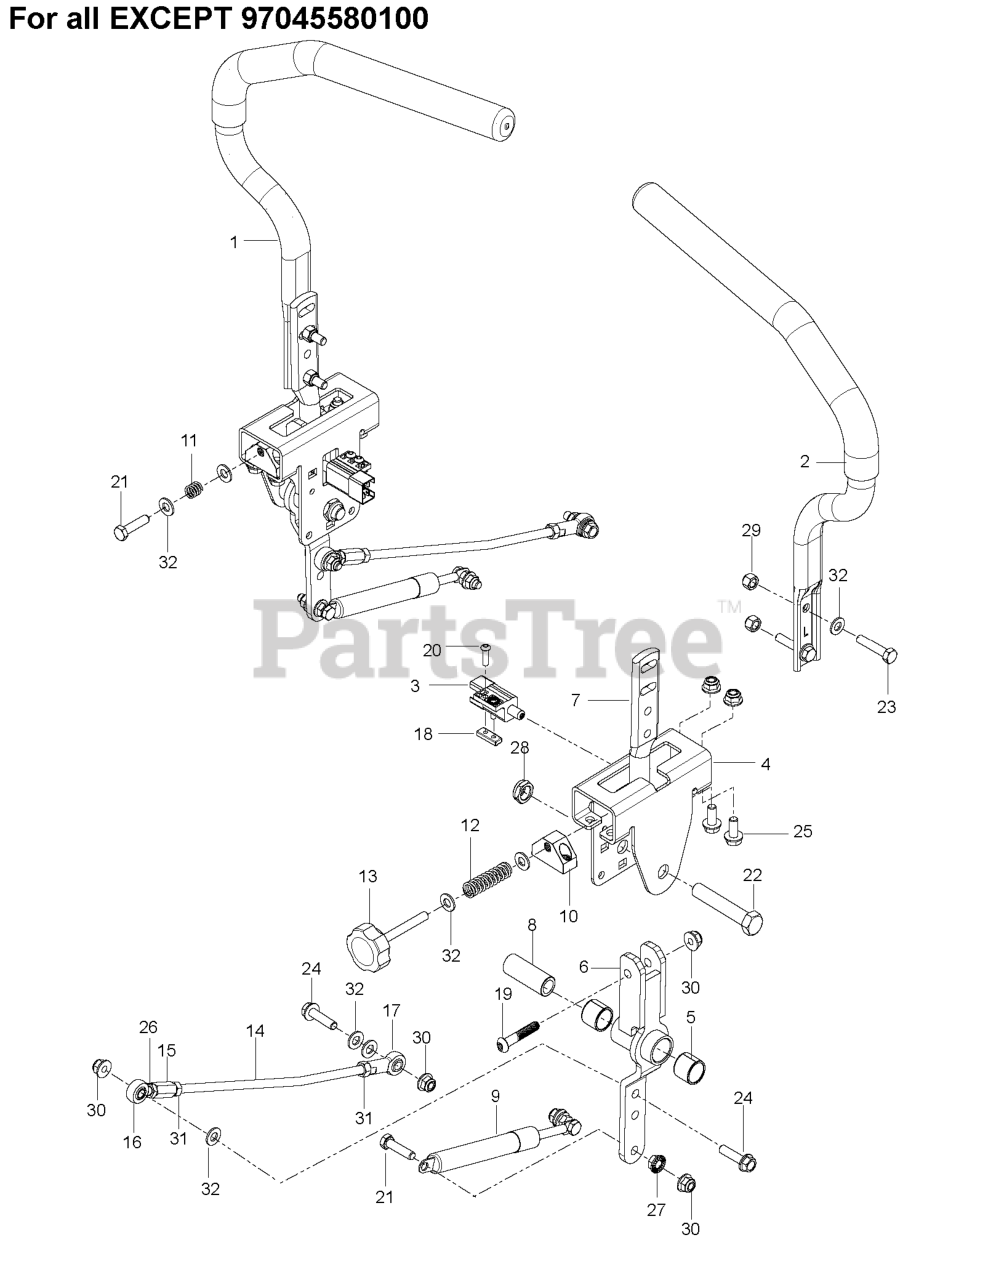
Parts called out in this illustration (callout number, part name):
1	TUBE.LEVER.CONTROL.ZTR.RT.428
2	TUBE.LEVER.CONTROL.ZTR.LT.428
3	SWITCH INTERLOCKT
4	BRACKET.CONTROLS.ZTR.X431
5	BEARING.PT.750
6	CONTROL.WELDMENT.RZ
7	LEVER.HANDLE MOUNT
8	SPACER.PIVOT.CONTROL
10	BLOCK TRACKING CONTROL ZTR
12	SPRING COMPRESSION 2.0
14	ROD, CONTROL
15	ROD END COUPLER
16	ROD.END.MALE.LH.THREAD
17	JOINT.HEIM.FEML.5/16.RH.THREAD
18	PLATE NUT ZTR
19	SCREW 5/16-18 X 1 3/4 BTN-HD
20	SCR #10-24 X .75 SKT HD BLK
21	BOLT.5/16-18X1-1/4 FULL.THREAD
22	HCS 1/2-13 X 2-3/4 GD 5 ZD
23	CAPSCREW 5/16 X 1/1/2 HEX HEAD
24	HHFS 5/16-18 X 1.25 TPBLT GD 5
25	HHFS 5/16-18 X 3/4
26	NUT 5/16F LEFTHAND
27	NUT 5/16C WHIZ
28	NUT 1/2-13 HEX JM NYL
29	NUT 5/16 NYLOC
30	5/16-18 NYLOC FLANGE NUT
32	WASHER
